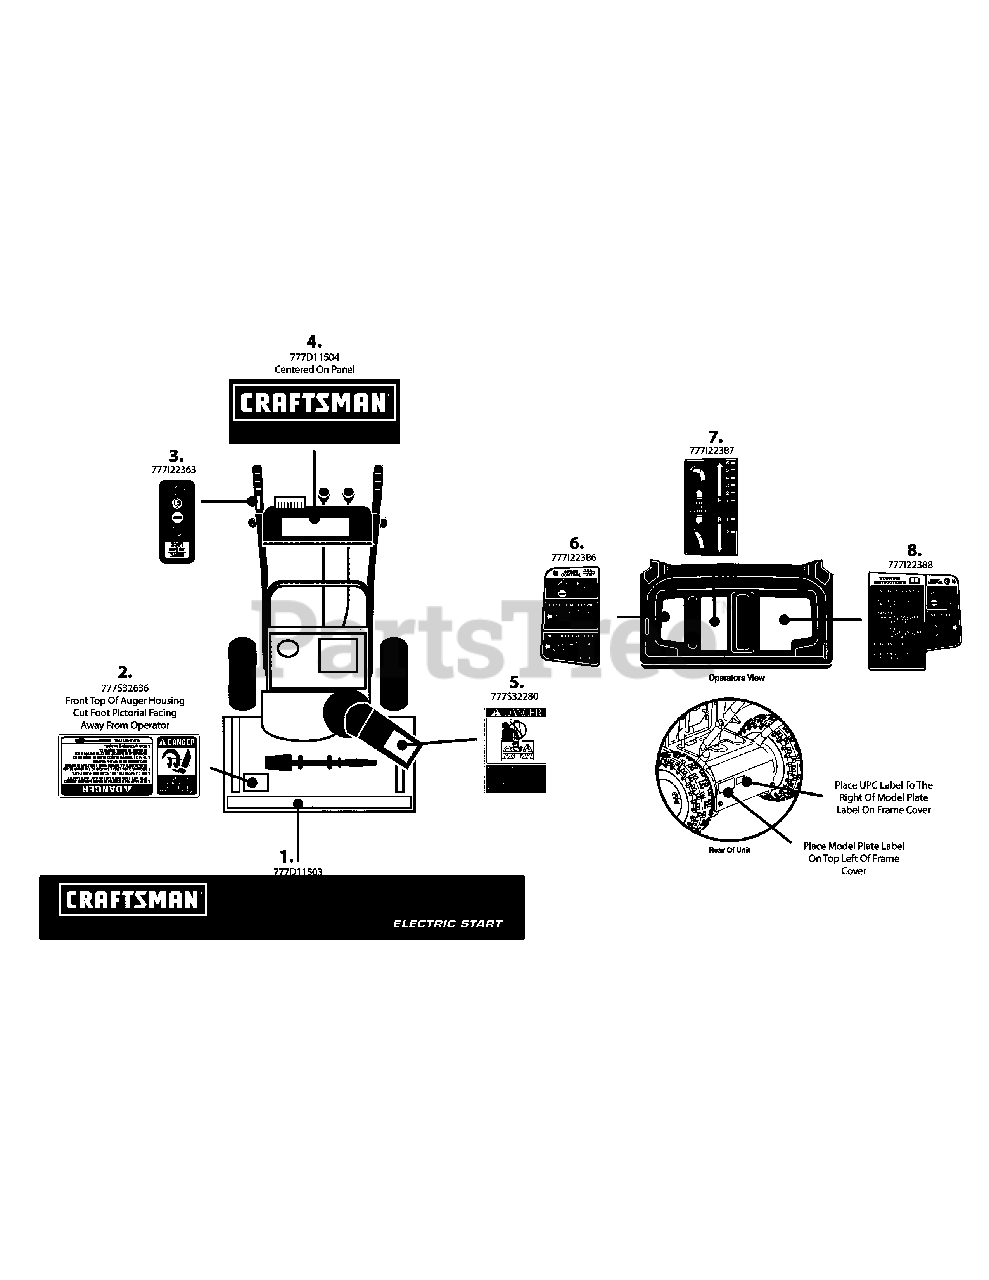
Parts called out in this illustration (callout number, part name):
1	LABEL-SNOW CRAFTSMAN PRO 45"
2	LABEL-SNOW HOUSING
4	LABEL-SNOW PANEL 6 STYLE CRAFTSMAN
5	LABEL-CHUTE
6	LBL:SNO: 8 STYLE
7	LBL:SNO:8 STYLE
8	LBL:SNO: 8 STYLE R
